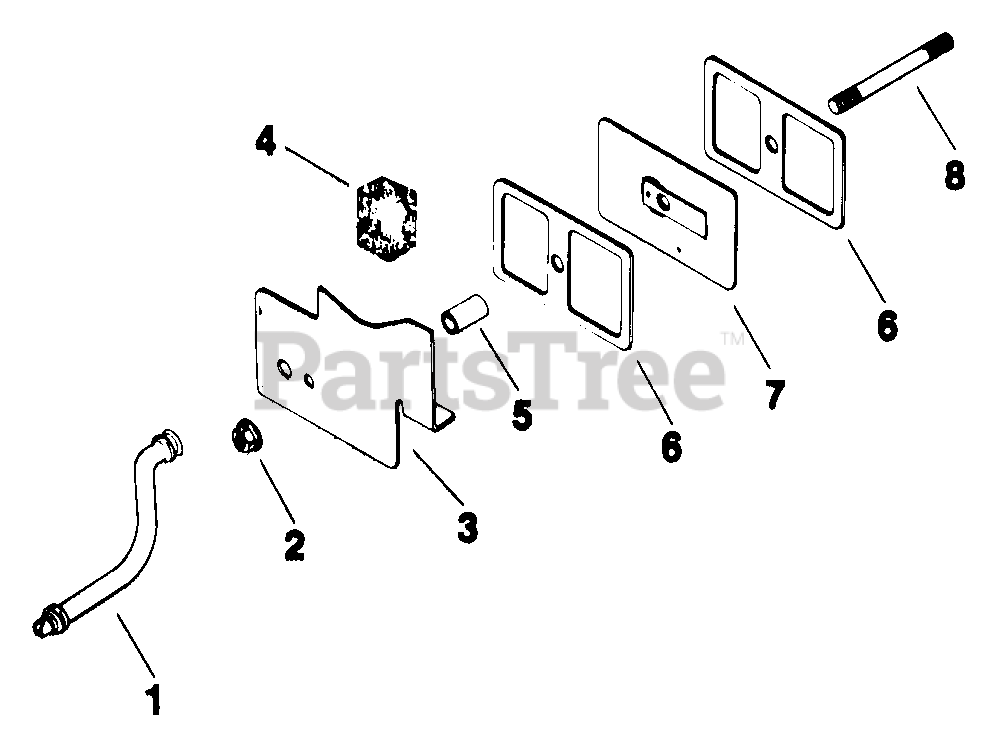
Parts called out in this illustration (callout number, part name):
1	HOSE
1	HOSE, BREATHER-(#DSC)
2	PALNUT, 1/4-20
3	VALVE COVER ASSEMBLY
4	FILTER, BREATHER
5	SEAL, BREATHER
7	BREATHER - DISCONTINUED
8	STUD,1/4-20x3-9/16"-DISCONTINUED
